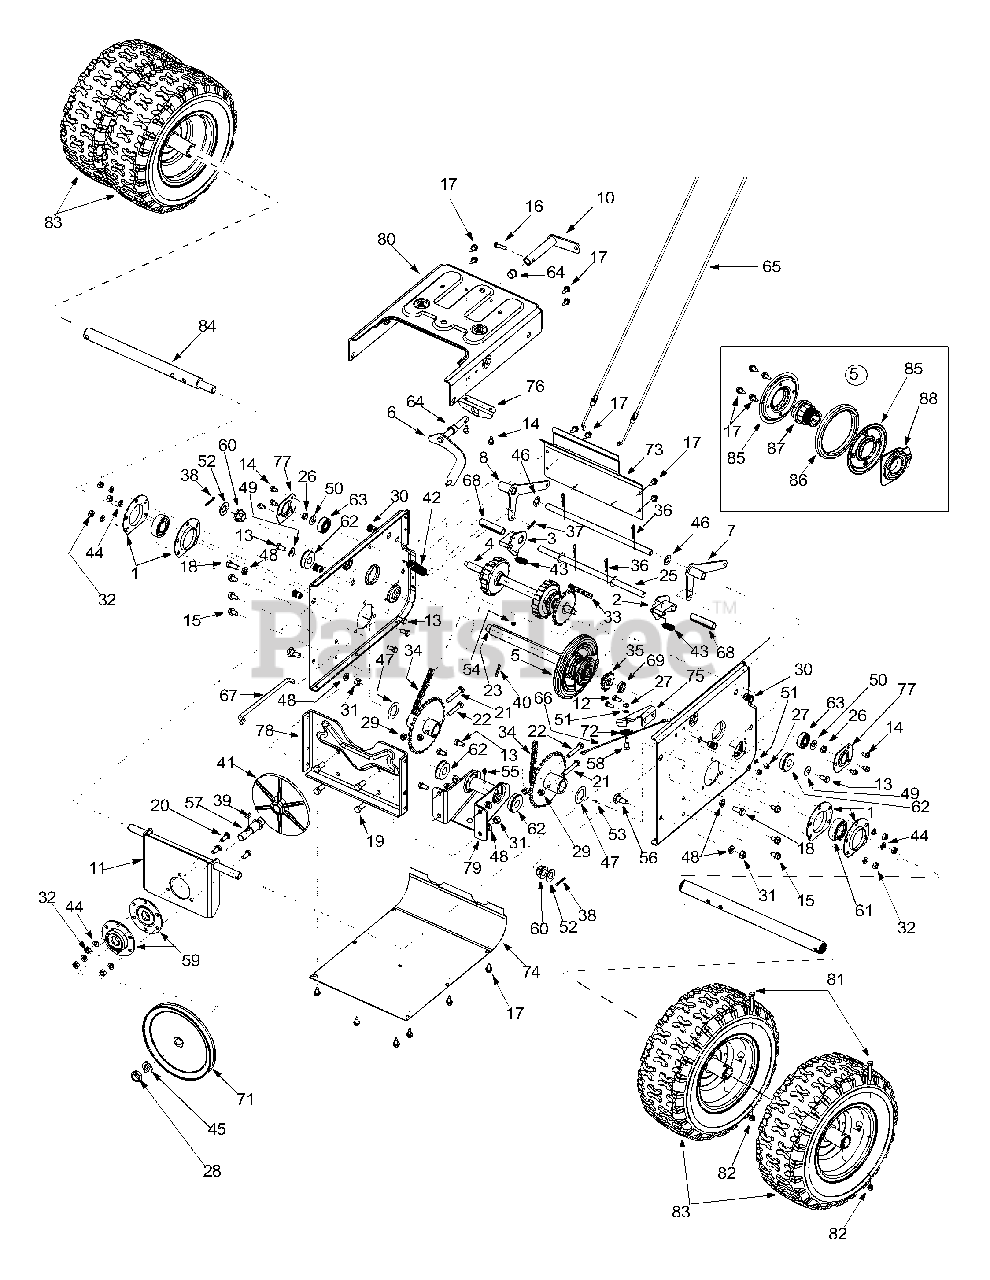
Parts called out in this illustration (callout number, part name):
1	Bearing Housing
2	Dogg Assembly LH
3	Dogg Assembly RH
4	Shift Assembly
5	Friction Wheel Assembly
6	Shift Rod Assembly
7	Actr. Bracket Assembly: Auger
13	Hex Screw 5/16-18 x .625"
14	TT Screw 1/4-20 x 0.5"
15	TT Screw 5/16-18 x 0.625"
16	TT Screw 1/4-20 x 1.0"
17	TT Screw 1/4-20 x .625"
18	Hex Screw 3/8-16 x .880"
19	Hex Screw 3/8-16 x .880"
20	Hex Screw 5/16-18 x 0.75"
21	Hex Screw 5/16-18 x 2.0"
22	Hex Screw 5/16-18 x 1.75"
23	Drive Shaft
25	Actr. Shaft: Drive
26	Jam Nut
27	Hex Nut 1/4-28
28	Jam Nut
29	Lock Nut
30	Nut Insert
31	Hex Nut 3/8-16
32	Hex Nut 5/16-18
33	Chain: Endless
34	Chain
35	Sprocket
36	Hairpin Clip
37	Hairpin Clip
38	Cotter Pin
39	Key
40	Spring Pin
41	Drive Plate
42	Extension spring
43	Extension Spring
44	Lock Washer 5/16
45	Lock Washer 5/8
46	Flat Washer .53 x .93 x .050
47	Flat Washer 1.030 x 1.620 x .030
48	Lock Washer
49	Bell Washer
50	Flat Washer .406 x .875 x .059
51	Lock Washer 1/4
52	Flat Washer .64 x 1.24 x .06
53	Grease
54	Lubricant
55	Lube Fitting: 3/16 Drive
56	Shoulder Screw
57	Spindle: drive Plate
58	C Screw 1/4-28 x .375"
59	Bearing Housing
60	Hex Flange Bearing
61	Bearing: Self-Aligning
62	Ball Bearing
63	Ball Bearing
64	Flange Bushing
65	Steering Cable
66	Idler Cable: Auger
67	Clutch Rod: Drive
68	Split Spacer
69	Spacer
71	Drive Pulley
72	Cable Roller
82	Lock Nut
84	Axle: Wheel
85	Friction Plate
86	Friction Wheel Rubber
87	Friction Wheel Hub
88	Friction Wheel Bearing
